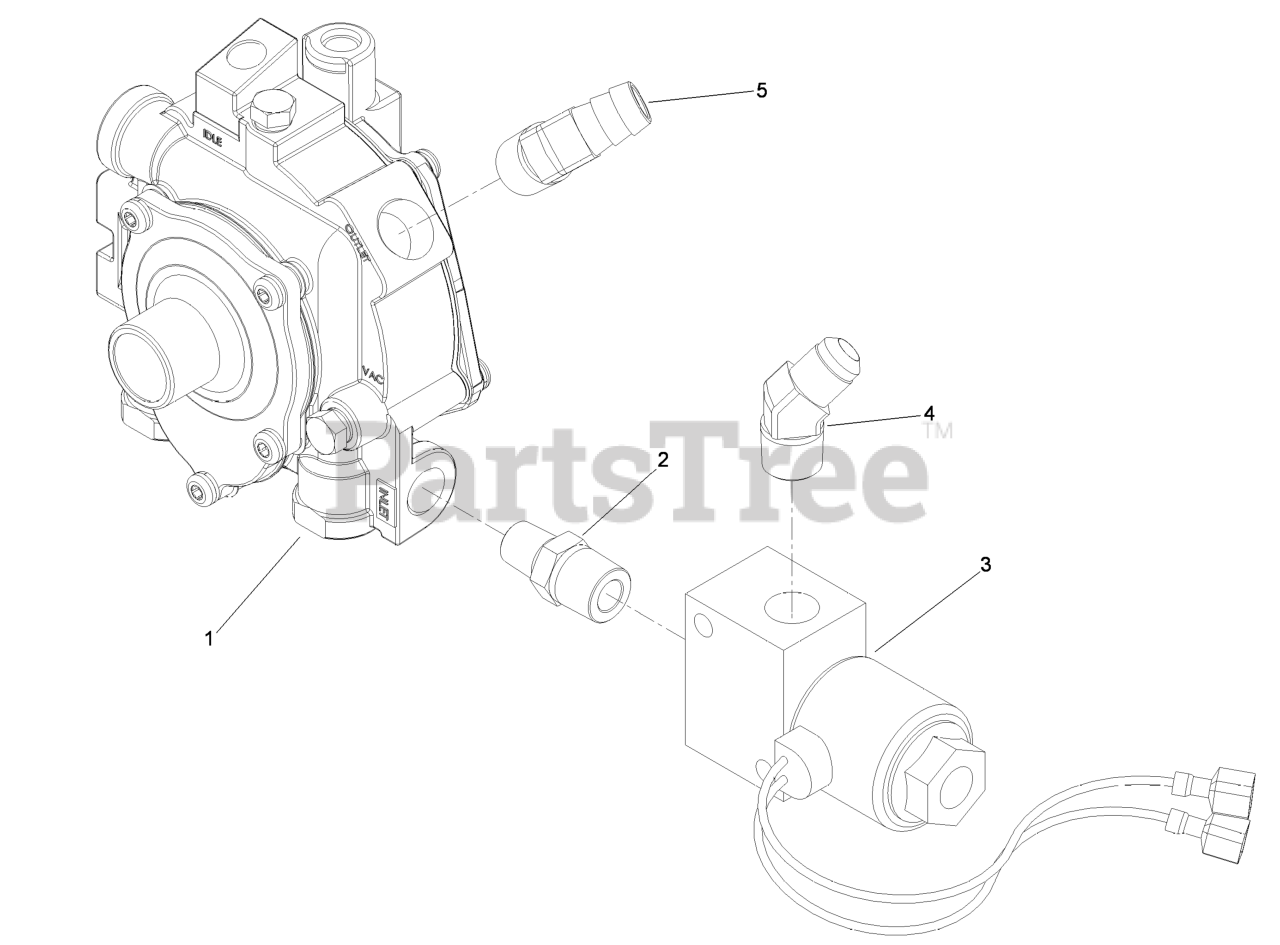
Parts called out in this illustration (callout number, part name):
1	Regulator-Lp, T60
2	COUPLING-PIPE, MALE
3	LPG SOLENOID VALVE ASM
